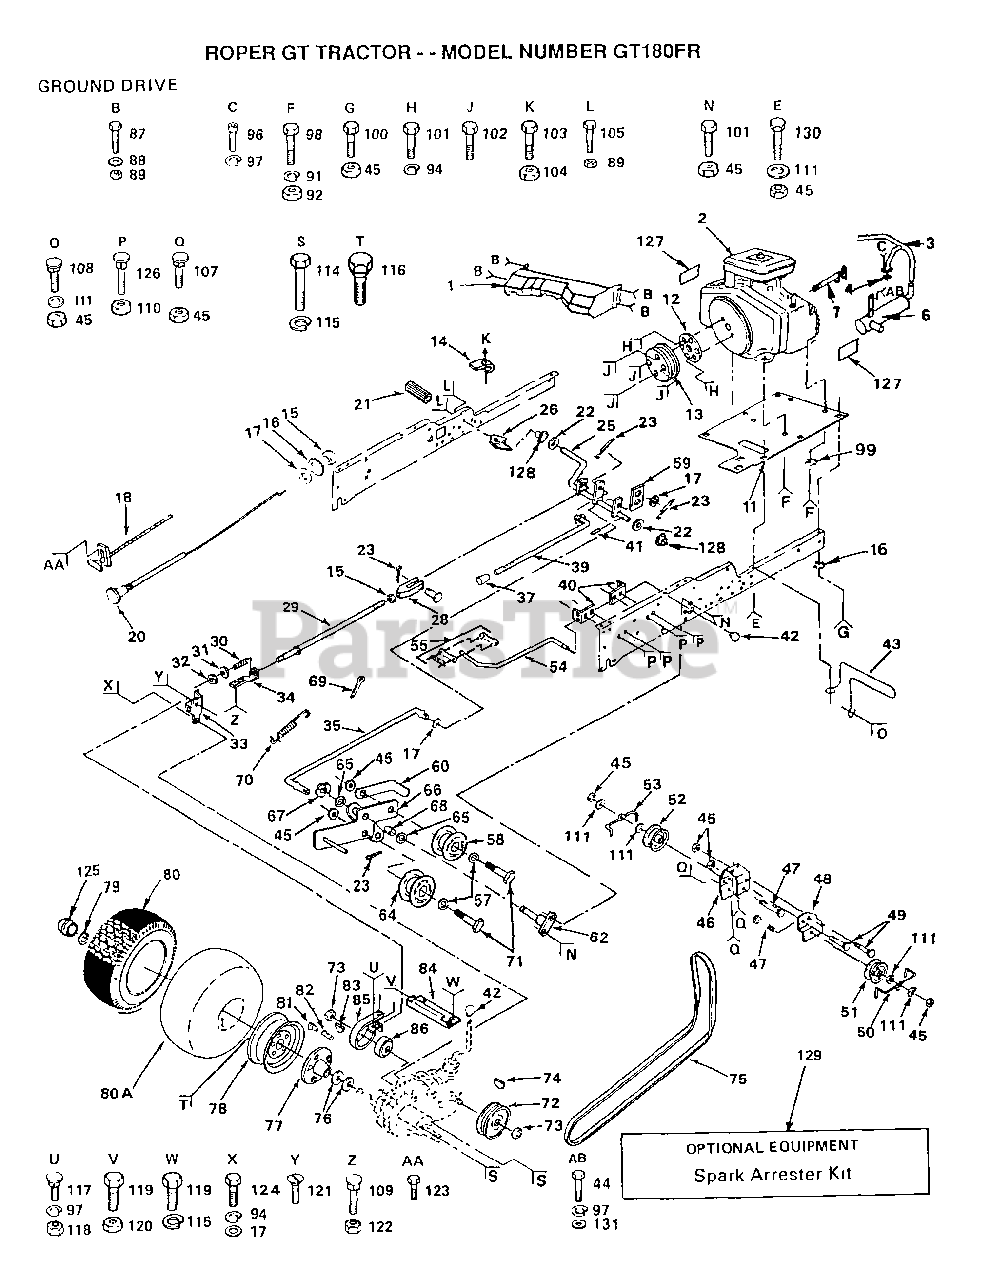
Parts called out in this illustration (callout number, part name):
11	"ENG. T, BASE"
12	ADAPTER T
14	ACT-SWITCH T
16	LOCKWASHER
17	WASHER
21	PEDAL COVER T
22	WASHER
25	SHAFT ASSY GT
26	BRKT SWITCH GT
28	YOKE GTV
29	BRAKE ROD T
30	SPRING T
31	WASHER
33	BRAKE BRKT ASSY T
34	GUIDE ROD T
35	ROD CLUTCH GTV
36	CLEVIS PIN T
37	PLUNGER CAP T
40	ROD BRACKET GT
41	ROLL PIN STD
42	KNOB
43	GUARD MUFFLER HYT
47	BOLT
49	BOLT
50	BELT GUARD T
51	IDLER-FLAT T
52	PULLEY V IDLR GTV
53	BELT GUARD GT
54	ROD SHIFT HI LO
55	CONNECTING LINK
56	LOCKNUT
57	WASHER
59	RETAINER SPRING
60	RETAINER BELT
62	BRACKET ASSY GTV
65	WASHER T
66	BRACKET CLUTCH
67	KLIP RING
68	"LY, BEARING"
69	COTTER PIN
70	SPRING EXT CLUTCH
71	BOLT
72	PULLEY GT
73	NUT STD
75	BELT-V.98.5.GD.DV
76	WASHER T
79	KLIP RING
80A	TUBE.23X8/10-12
81	VALVE CAP
82	VALVE STEM LT
86	BRAKE DRUM T
88	WASHER
91	LOCKWASHER
92	NUT.HEX.5/16-18
94	LOCKWASHER
97	LOCKWASHER
98	BOLT
99	LOCKWASHER.5/16.E
101	BOLT
102	SCREW
103	SCREW
105	BOLT LT
107	BOLT
108	BOLT.3/8-14X1.25
111	WASHER GT
114	BOLT
115	LOCKWASHER
117	BOLT T
119	BOLT
120	NUT GTV
121	SCREW
123	SCREW
125	CAP-HUB GT
126	BOLT
128	NYLINER T
129	SPARK ARREST KIT
130	BOLT
